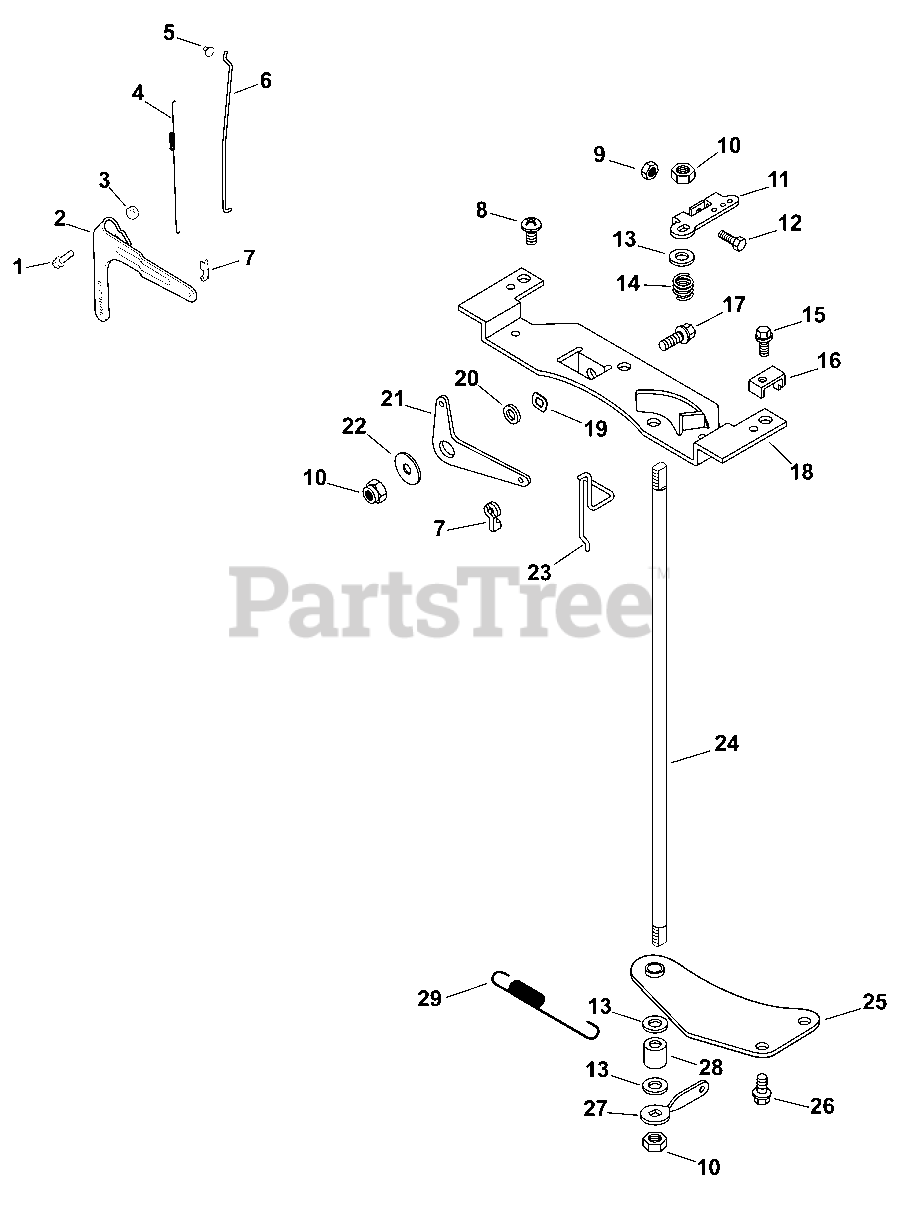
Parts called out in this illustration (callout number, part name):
1	BOLT, RD HD SQ NECK M6X1.0X25
2	LEVER, GOVERNOR-USE 24 090 57-S
3	NUT, FLG M6X1.0
4	SPRING, LINKAGE
5	BUSHING, LINKAGE RETAINING
6	LINKAGE, THROTTLE
7	BUSHING, THROTTLE LINKAGE
8	SCREW, PHL HD 11-16X3/4"
9	NUT, M4X0.7
10	NUT, LOCK M6X1.0
11	LEVER, THROTTLE CONTROL
12	SCREW, CAP M4X.7X30
13	WASHER, FLAT 1/4"
14	SPRING, THROTTLE SHAFT
15	SCREW,FLG THD FRM M5X0.8X16-(#25086398S)
16	CLAMP, CABLE
17	SCREW, FLG M6X1.0X16
18	BRACKET, CONTROL-USE 24 126 219-S
19	WASHER, SPRING 3/8"
21	LEVER, CHOKE
22	WASHER, FLAT 1/4"
23	LINKAGE, CHOKE
24	SHAFT, THROTTLE
25	BRACKET, THROTTLE SHAFT-USE 24 126 162-S
26	SCREW,FLG THD FRM M6X1.0X16-(#25086397S)
27	LEVER, THROTTLE CONTROL
29	SPRING, GOVERNOR (BLUE)
